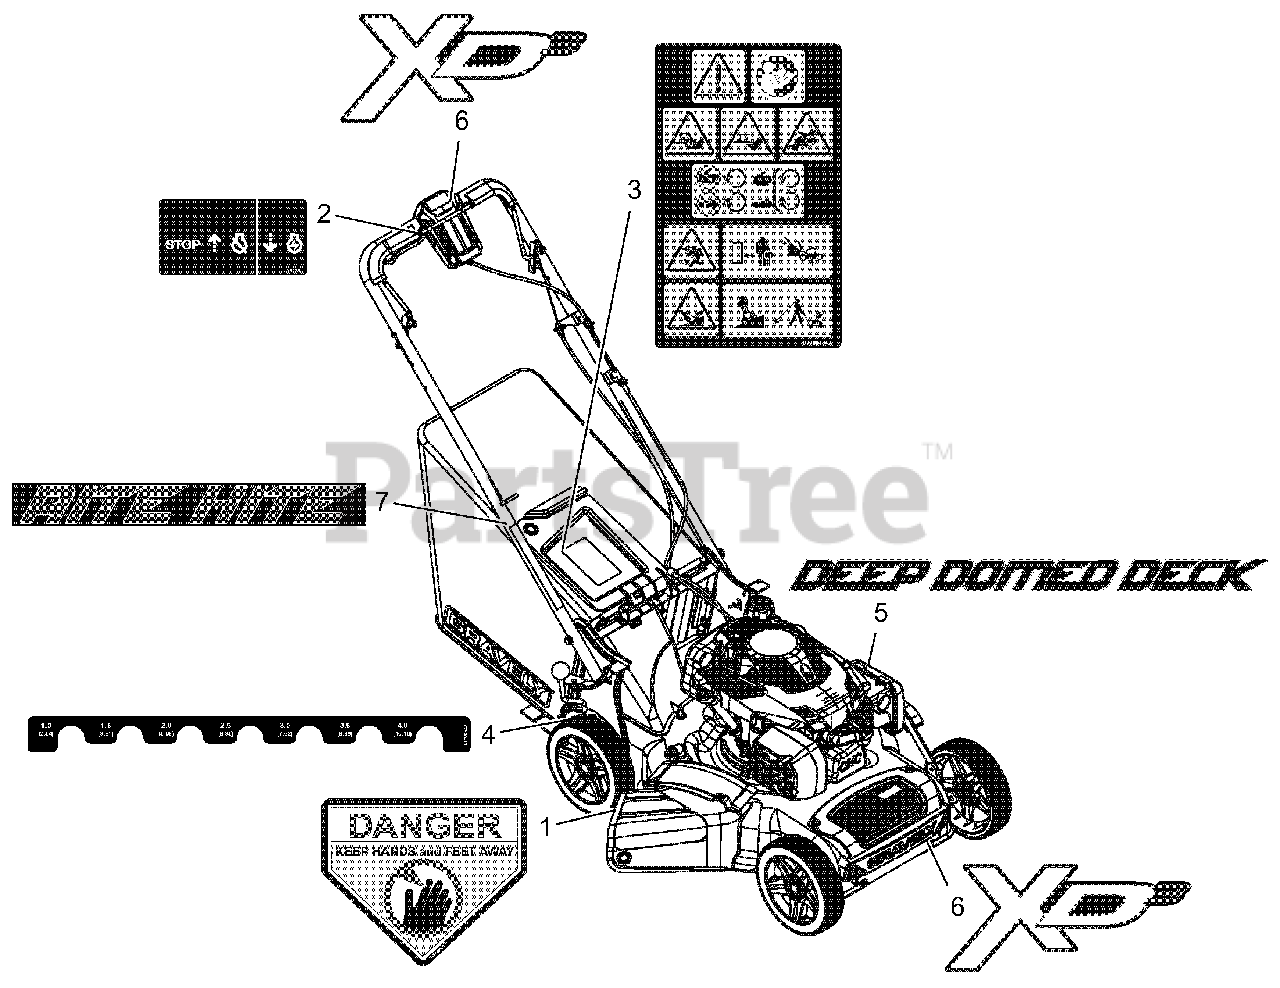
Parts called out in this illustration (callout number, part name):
1	DECAL, DANGER
2	DECAL, ENGINE CONTROL
3	DECAL, MAIN SAFETY WAW LM
4	DECAL, HOC
5	DECAL, DEEP DOME DECK
6	DECAL, GRAVELY XD3 STYLE
7	DECAL, RITE HITE
